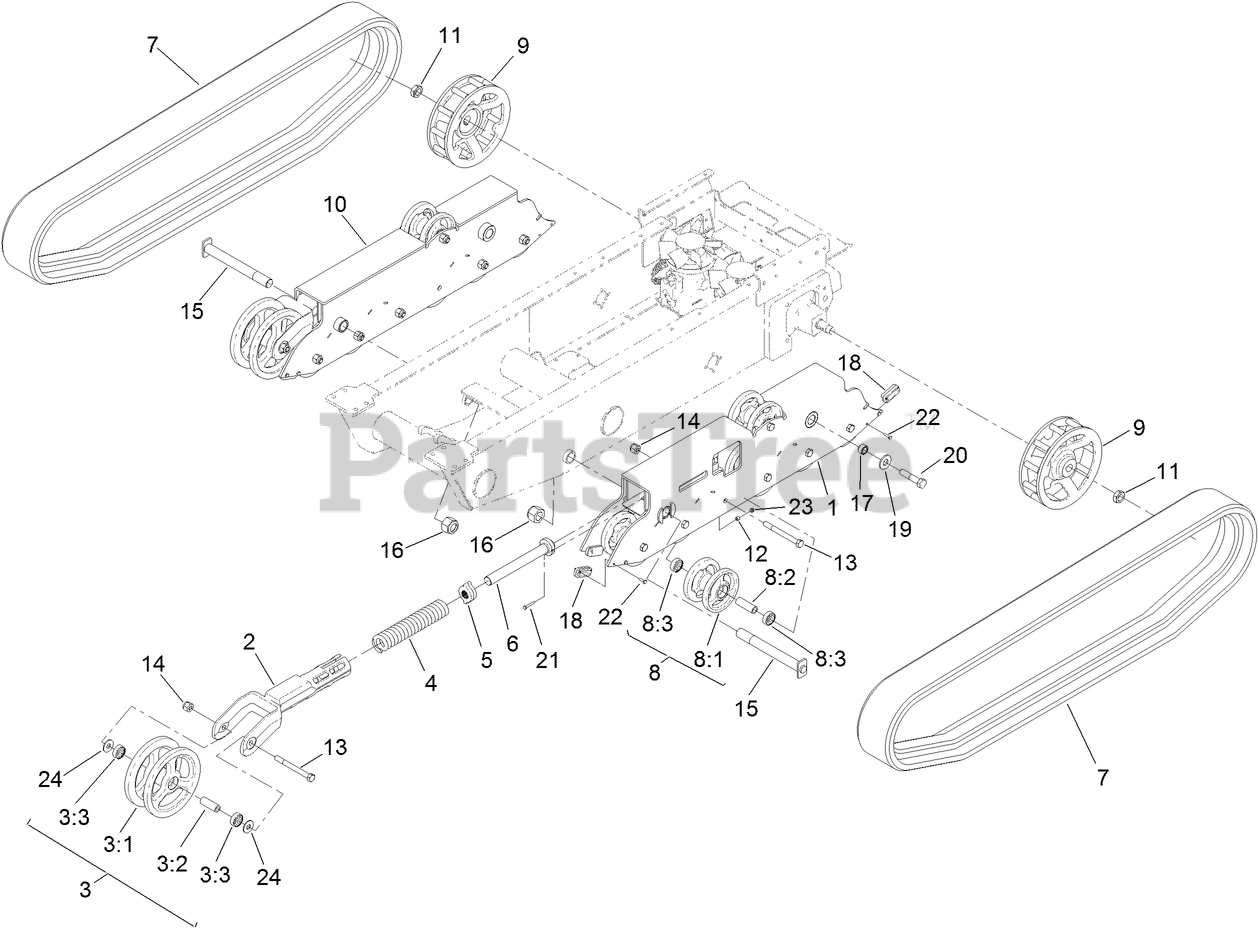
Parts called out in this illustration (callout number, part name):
1	MOUNT-WHEEL, LH
2	ARM-TENSIONER
3	TENSIONER WHEEL ASM
3:1	WHEEL-TENSIONER
3:2	SPACER-WHEEL, TENSIONER
3:3	BEARING-BALL
4	SPRING-COMPRESSION
5	BLOCK-TENSIONER
6	BOLT-TENSIONER
7	TRACK
8	ROAD WHEEL ASM
8:1	WHEEL-ROAD
8:2	SPACER-WHEEL
8:3	BEARING-BALL
9	WHEEL-DRIVE
10	MOUNT-WHEEL, RH
11	NUT-LOCK
12	SPACER
13	SCREW-HH
14	NUT-HEX
15	PIN-TRACK
16	NUT-HH
17	SPACER-TRACK, OUTSIDE MOUNT
18	BLOCK-TRACK
19	WASHER
20	SCREW-HH
21	SCREW-HH
22	SCREW-HH
23	NUT-HHF
24	WASHER-FLAT
